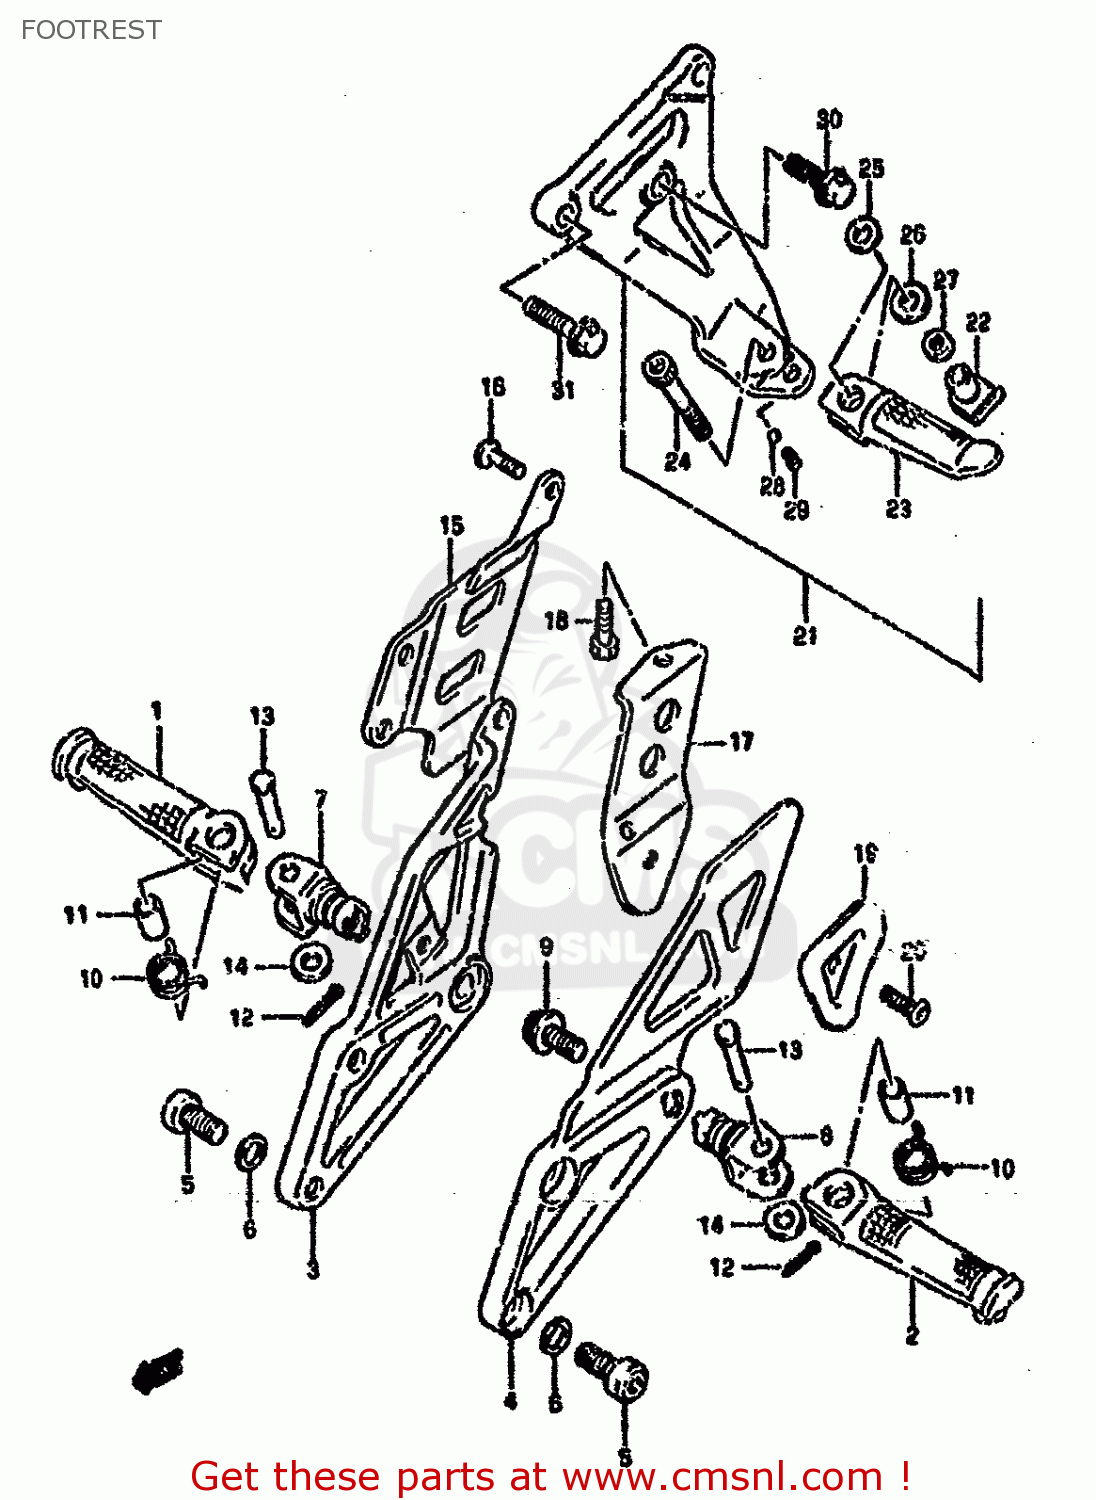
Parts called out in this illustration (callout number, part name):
1	BAR,FOOTREST,R
2	BAR,FOOTREST,L
3	BRACKET,FR FOOTREST,R
4	BRACKET,FRONT FOOTREST
5	BOLT
6	WASHER
7	HOLDER,FOOTREST,RIGHT
8	HOLDER,FOOTREST,L
9	BOLT(10X24)
10	SPRING
11	SPACER(8.1X12X22)
12	PIN 20X15
13	PIN
14	WASHER(8.5X18X1)
15	GUARD,FRONT FOOTREST,RIGHT
16	BOLT
17	REINFORCEMENT,FOOTREST,L
18	SCREW
19	PLATE,REINFORCEMENT,L
20	SCREW(6X12)
21	FOOTREST ASSEMBLY,PILLION
22	BOSS,PILLION FOOTREST,R
23	BAR,PILLION FOOTREST R
24	BOLT
25	WASHER(8.5X18X1)
26	WASHER
27	NUT
28	BALL
29	SPRING
30	BOLT
31	BOLT
